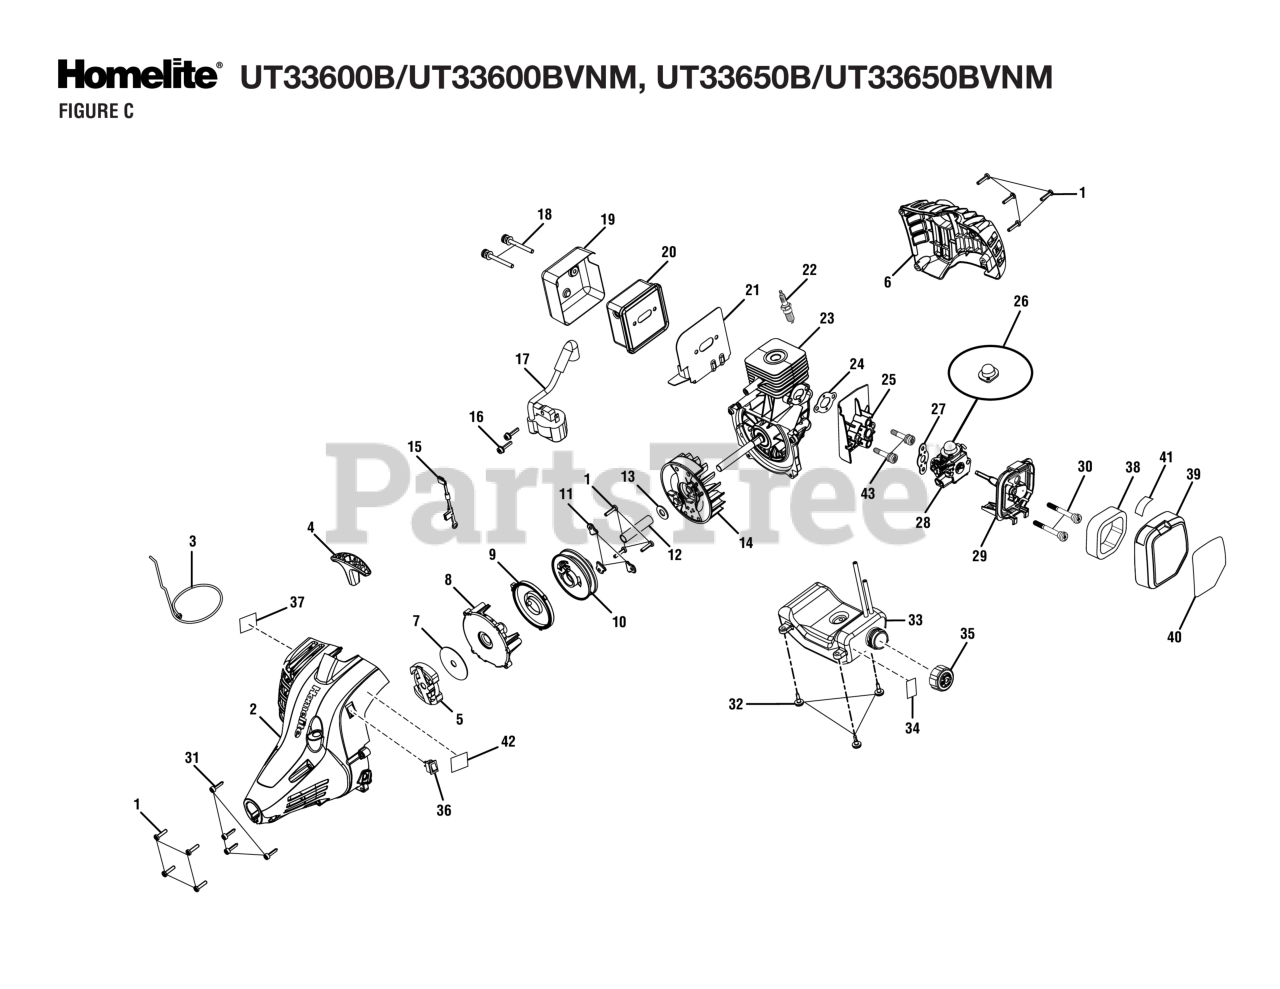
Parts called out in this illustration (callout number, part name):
1	Screw (M4 x 20 mm, T20 Torx Pan Hd. S.T.)
2	Starter Housing Assembly
3	Starter Rope (42 in.)
4	Pulley Handle
5	CLUTCH ASSEMBLY
6	Rear Housing
7	Washer (ID9.63 x OD50.75 x 1.10t)
8	Starter Housing
9	Spring & Container Assembly
10	Starter Pulley Assembly
11	Pulley Retainer
12	Spacer Tube
13	Washer (ID9.75 x OD20 x 1.6t)
14	Flywheel Assembly
15	Lead Assembly
16	Screw w/Washer (M4 x 19 mm, T20 Torx Pan Hd. S.T.)
17	Ignition Module
18	Screw w/Washers (10-24 x 2-1/8 in., T25 Torx Truss Hd.)
19	Muffler Housing
20	Muffler Assembly (Non "A" versions)
21	Muffler Gasket
22	SPARK PLUG CHAMPION - RCJ-6Y
23	Short Block Assembly
24	Inner Heat Dam Gasket
25	Heat Dam Deflector
28	Carburetor Assembly
29	Airbox Base Assembly
30	Screw (M5 x 45 mm, T20 Torx Truss Hd.)
31	Screw w/Washer (M4 x 16 mm, T25 Torx Truss Hd.)
32	Shoulder Screw w/Washer (M4 x 14 mm, T25 Torx Truss Hd.)
33	Fuel Tank w/Label & Cap Assembly
34	Fuel Tank Warning Label
35	Fuel Cap Assembly
36	Stop Switch (Momentary Contact)
37	Warning Label (Combustion)
38	Air Filter (Element)
39	Air Box Cover
40	Starting Label
41	Choke Label
42	Primer Bulb Location Label
43	Screw w/Washers (M5 x 30 mm, T25 Torx Pan Hd.)
